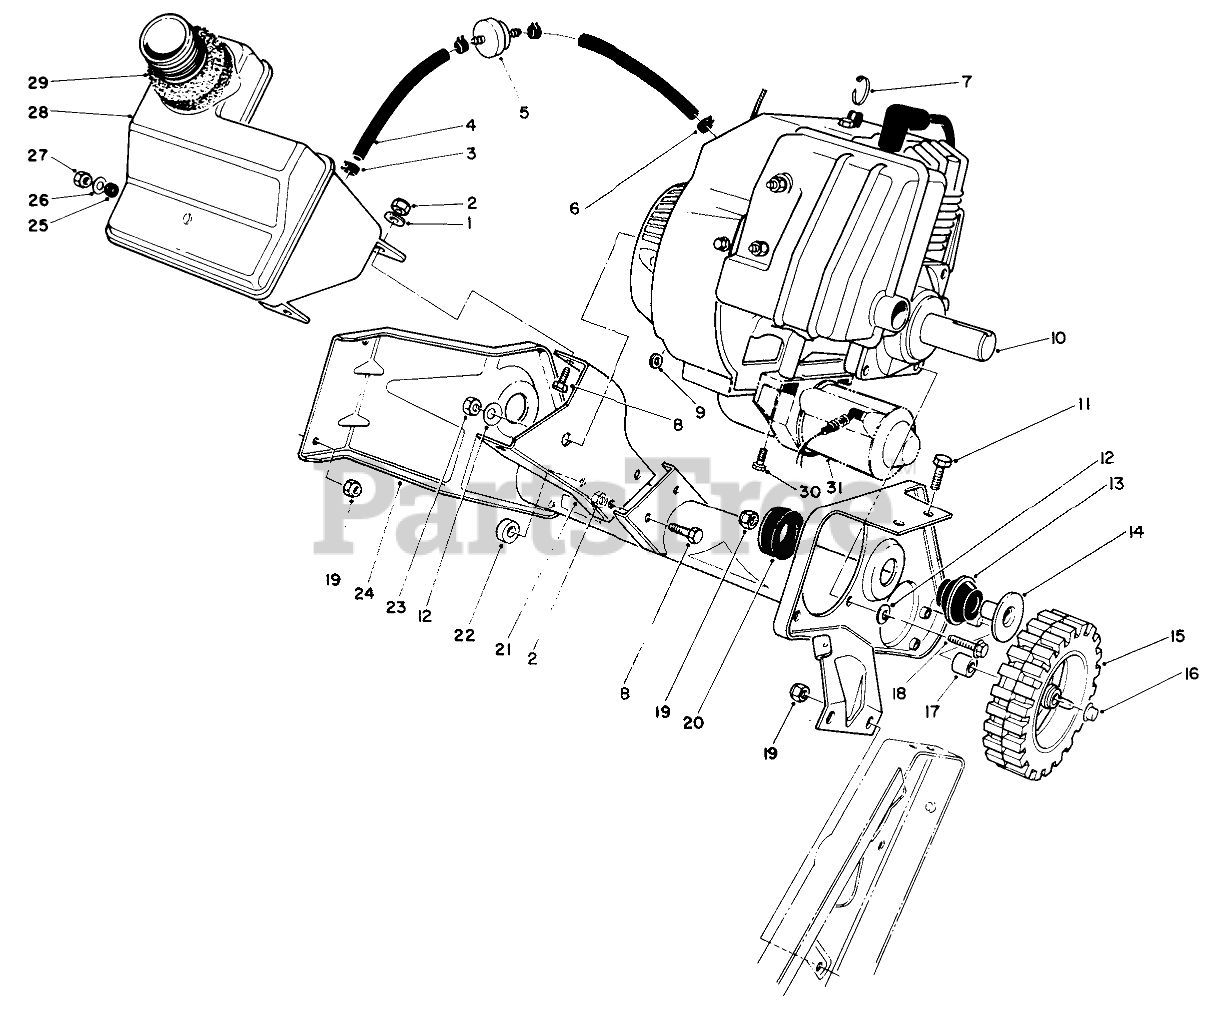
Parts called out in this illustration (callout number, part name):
1	WASHER-FLAT
2	NUT-LOCK, NI
3	Clamp
4	GAS LINE
5	FILTER-FUEL
6	CLAMP-HOSE
7	TIE-CABLE
8	SCREW-HH
9	SPACER-PLATE, PIVOT
10	Engine Assembly
11	SCREW-HH
12	WASHER-BELLEVILLE
13	MOUNT-REBOUND
14	SPACER TUBE
15	WHEEL
16	NUT-PUSH
17	SPACER-WHEEL
19	NUT-LOCK, NI
20	LOAD MOUNT
21	Support-Recoil
22	SPACER-WHEEL
23	NUT (F/W & PPP)
24	Wa-Frame
25	GROMMET-RUBBER
26	WASHER-PLAIN
27	NUT-LOCK, CONE
28	Tank-Fuel (Incl. Ref. #25)
29	SEAL-FOAM
30	SCREW
31	Starter Motor
